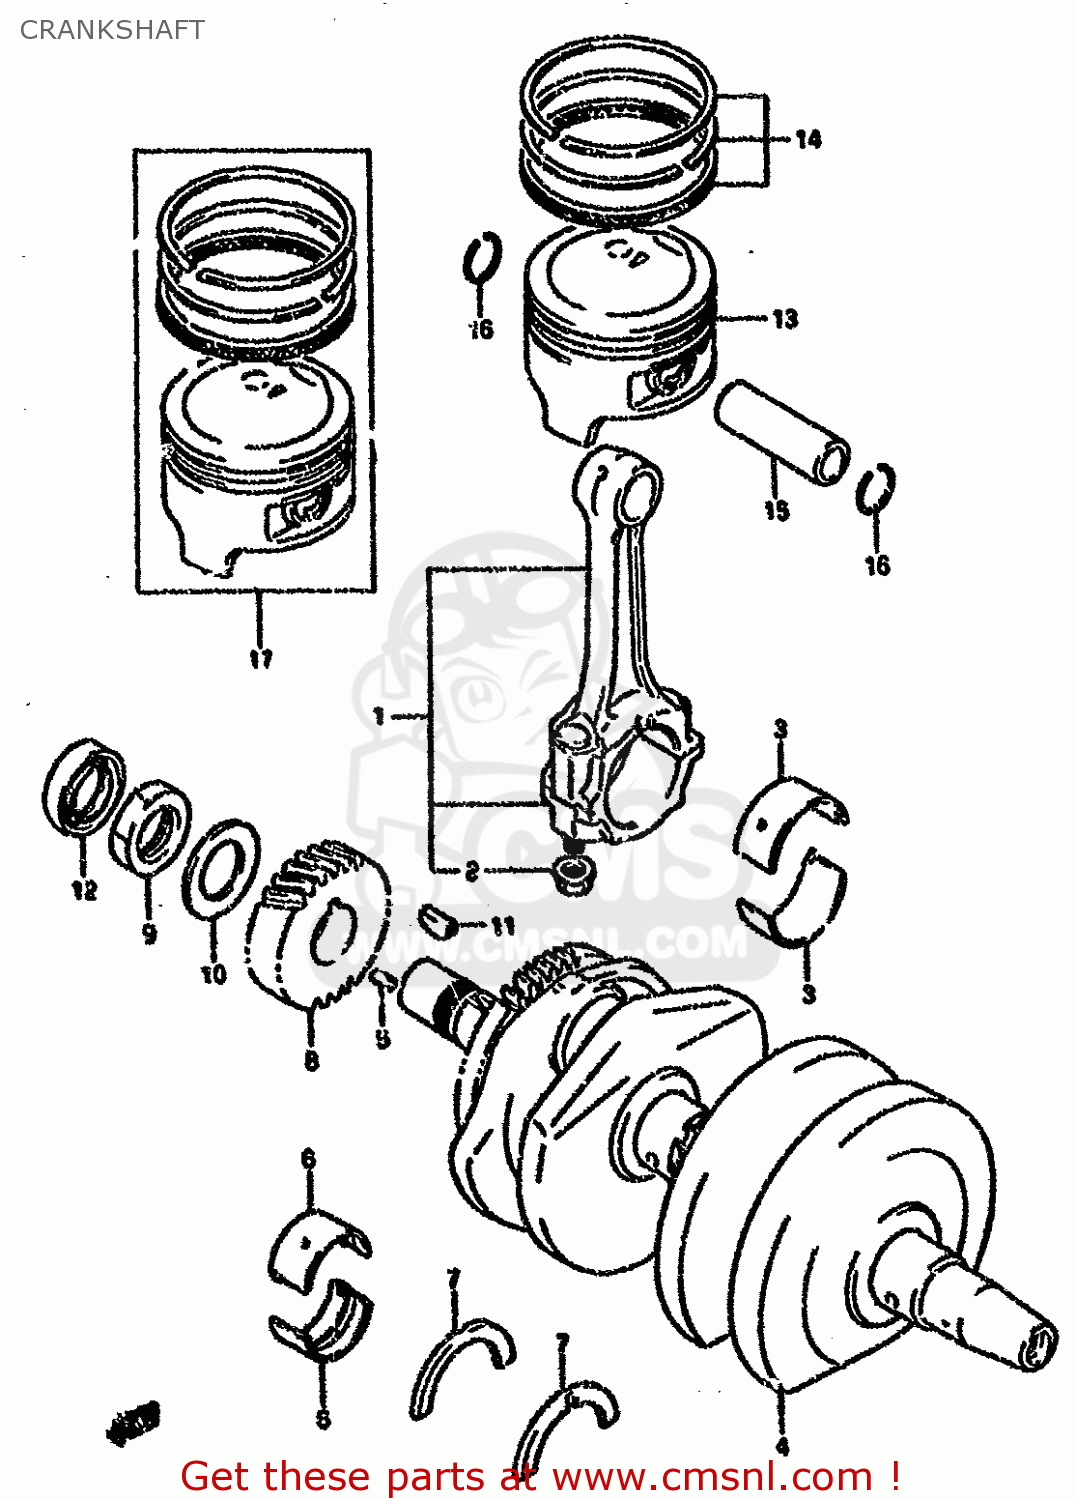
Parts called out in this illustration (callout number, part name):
1	ROD ASSEMBLY,CONNECTING
2	NUT
3	BEARING,CRANK PIN
4	CRANKSHAFT
5	PIN
6	BEARING,CRANKSHAFT(GREEN)
7	BEARING,CRANK THRUST
8	GEAR,PRIMARY DRIVE NO.28
9	NUT
10	WASHER
11	KEY
12	SEAL,OIL(22X40X8)
13	PISTON (74.00MM)
14	RING SET,PISTON
15	PIN,PISTON (18MM)
16	CIRCLIP,PISTON PIN
17	PISTON SET(OS:0.5)
